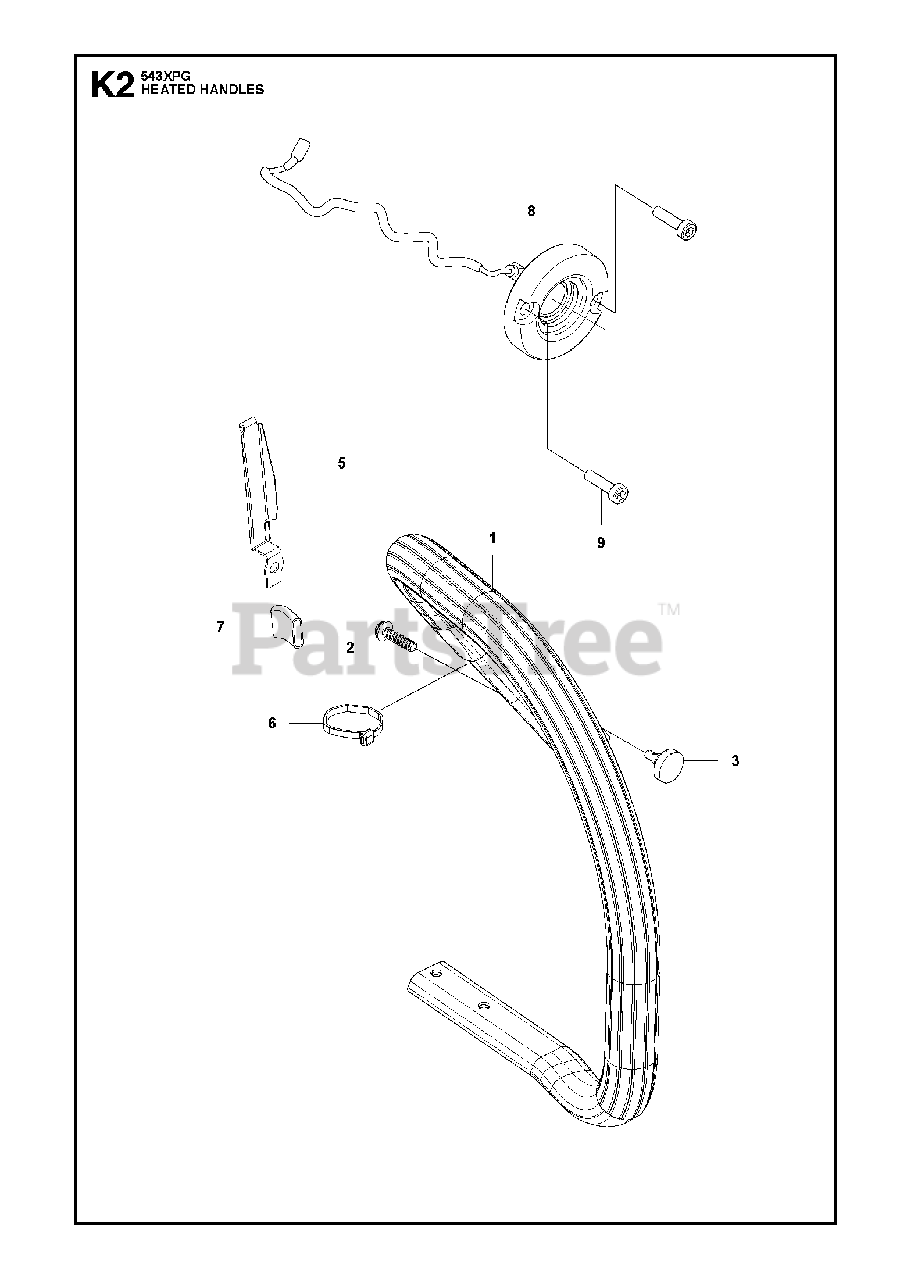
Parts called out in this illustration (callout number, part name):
1	FRONT HANDLE ASSY
2	SCREW (RPLS 267132210)
3	HELPER(P) Z285032150
5	PLATE T202032220
7	TUBE T202034860
8	COIL T202071410
9	BOLT
